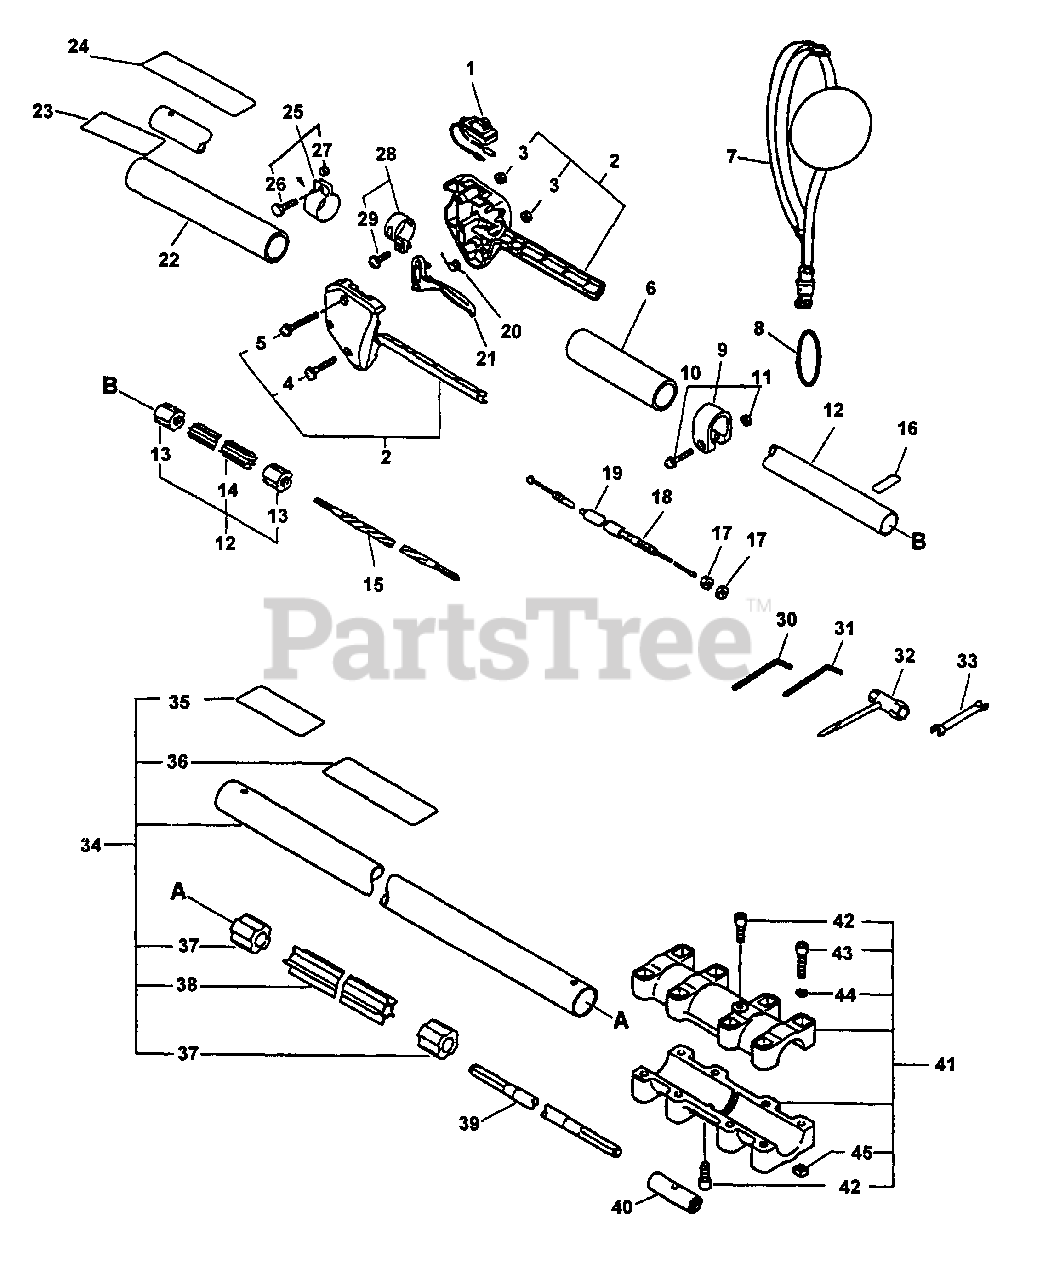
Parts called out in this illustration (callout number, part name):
1	IGNITION SWITCH ASSY
2	CONTROL HANDLE KIT
4	SCREW - 5X25
5	SCREW - 5X35
6	GRIP, HANDLE
7	SHOULDER STRAP ASSY
9	CLAMP KIT
10	SCREW - 5X28
12	MAIN PIPE ASSY
14	LINER - FLEXIBLE
15	DRIVESHAFT - FLEXIBLE
16	LABEL - ALIGNMENT
18	CABLE, THROTTLE
19	TUBE - VINYL
20	SPRING, TRIGGER
21	TRIGGER, THROTTLE
22	GRIP, HANDLE
23	LABEL - CAUTION
24	LABEL - CAUTION
25	CLAMP
26	BOLT - 5X18
28	CLAMP KIT
29	SCREW - 5X12
30	HEX KEY - 4mm
31	HEX KEY - 3mm
32	T-WRENCH - 17X19mm
33	SPANNER - 8X10mm
34	MAIN PIPE ASSY
35	LABEL - CAUTION
36	LABEL - CAUTION
38	LINER - FLEXIBLE
39	DRIVESHAFT - FLEXIBLE
40	CONNECTOR, SHAFT
41	CLAMP, MAIN PIPE
42	SCREW - 5X12
43	NUT - 5 -- SQUARE
44	LOCKWASHER - 5
45	SCREW - 5X25
